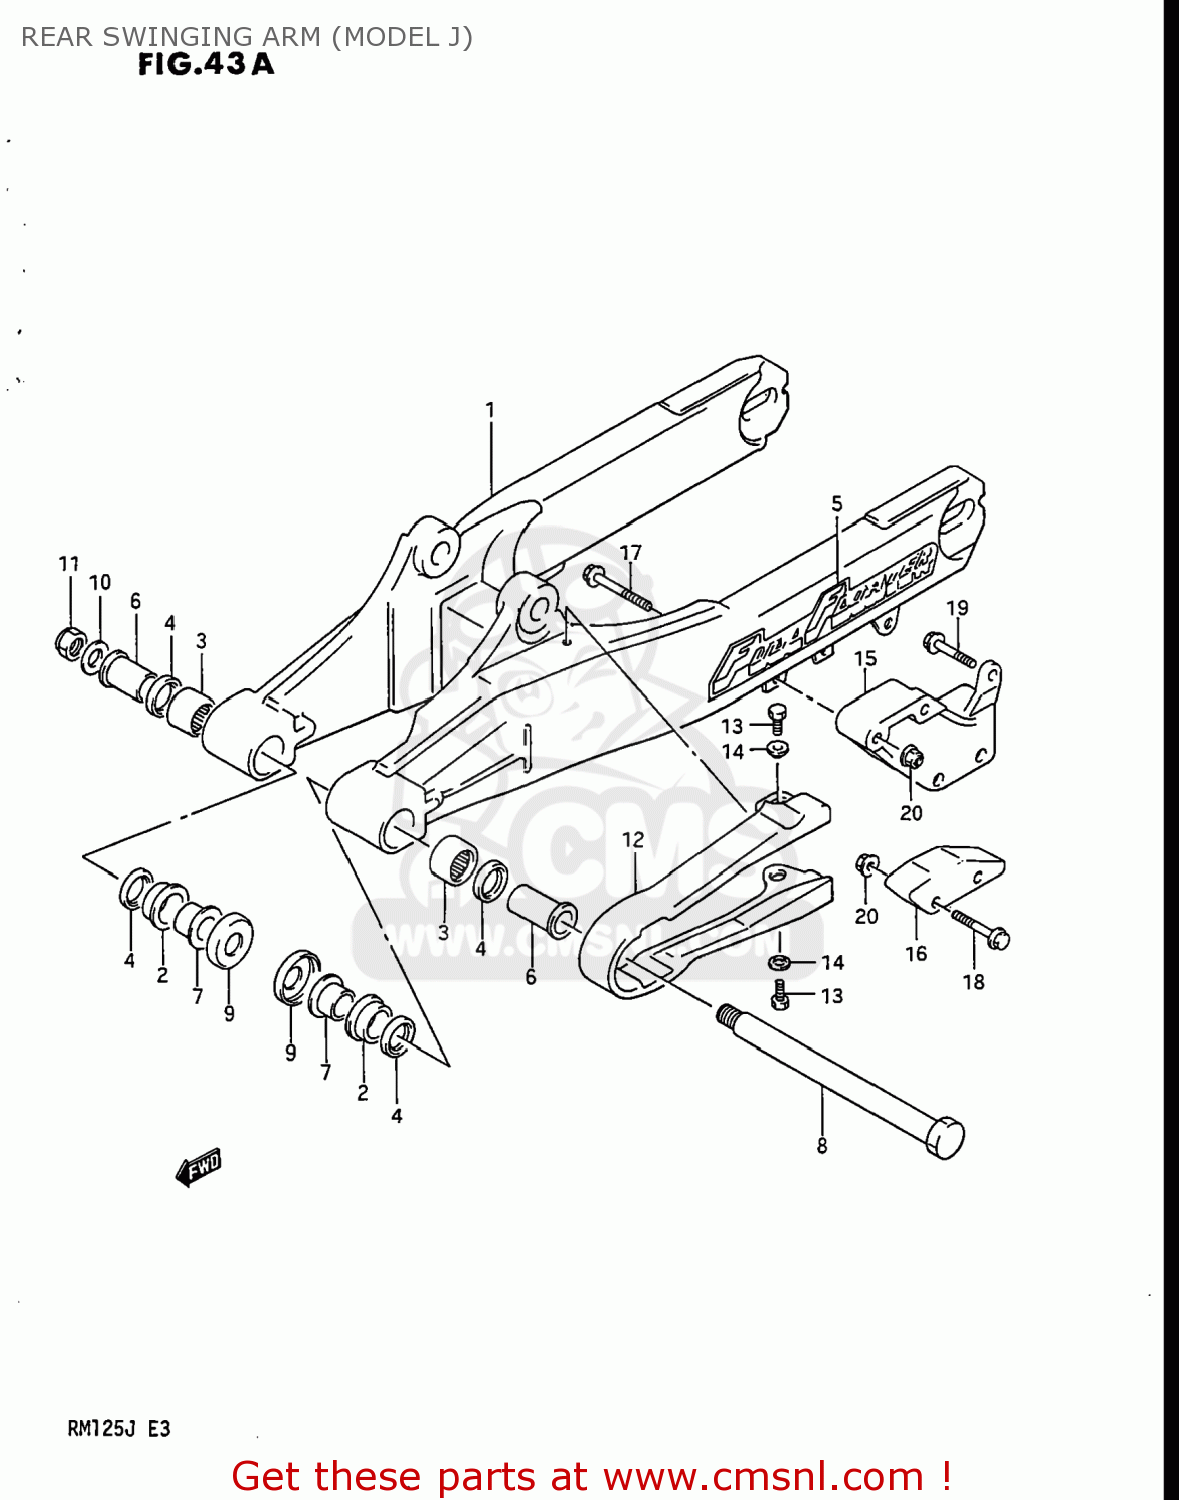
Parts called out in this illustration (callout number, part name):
1	SWING ARM ASSEMBLY,REAR
2	BUSHING,REAR SWING ARM PIVOT
3	BEARING(20X27X20)
4	OIL SEAL
5	LABEL (FRONT CARRIER WARNING)
6	SPACER,RR SWGARM PIVOT
7	SPACER,RR SWGARM PIVOT INNER
8	SHAFT,REAR SWING ARM PIVOT
9	COVER,RR SWGARM DUST SEAL
10	WASHER(14.2X24X2.3)
11	NUT
12	BUFFER,CHAIN TOUCH DEFENSE
13	BOLT
14	WASHER
15	GUIDE,CHAIN
16	DEFENSE,CHAIN GUIDE
17	BOLT
18	BOLT,UNDER
19	BOLT 6X20
20	NUT
